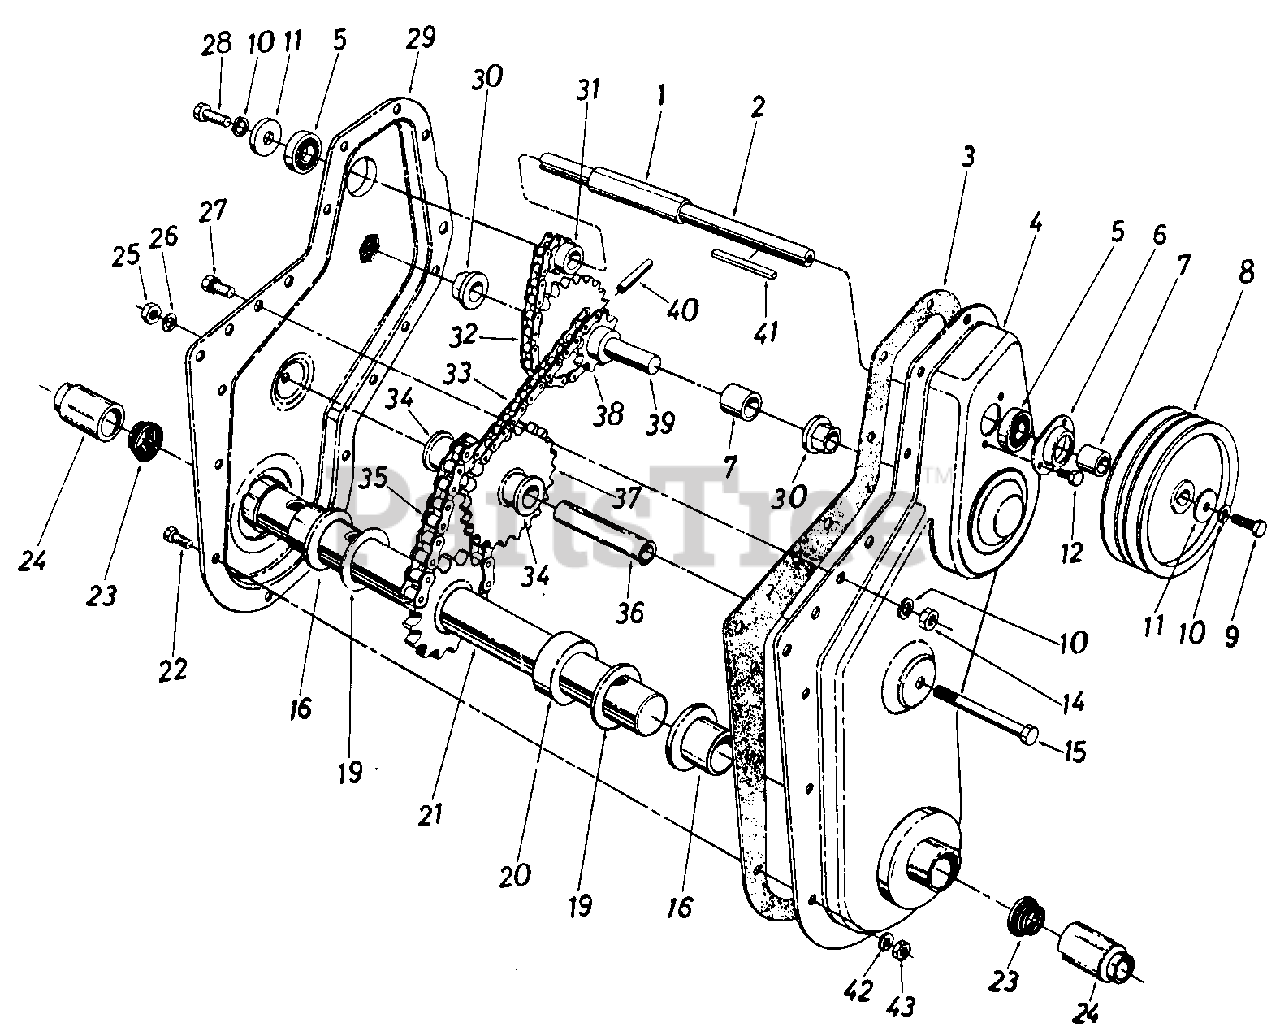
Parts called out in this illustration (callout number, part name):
2	SHAFT-JACK
3	GASKET
4	CHAIN CASE HALF-LH
5	BEARING-BALL
6	HOUSING-BRG
7	SPACER-.635 ID X .88 OD X 1.03
9	SCREW-HEX 5/16-18 X 10 SPEC
10	WASHER-LOCK-5/16
11	WASHER-FL-.312 X 1.125 X .125
12	SCREW-HEX WASH SF TAPP
14	NUT-HEX 5/16-18
15	SCREW-HEX 3/8-16 X 3.25
16	BEARING-KING PIN
19	WASHER-FL-1.03 ID X 1.62 X .03 HD
21	SHAFT-TINE
22	SCREW-HEX 1/4-28 X .62
24	CAP-DUST
25	NUT-HEX 3/8-16
26	WASHER-LOCK-3/8
27	SCREW-HEX SEMS 5/16-18 X 1.00
28	SCREW-HEX 5/16-18 X .62
29	CHAIN CASE HALF-RH
30	BEARING-HEX FLANGE
31	SPROCKET ASSY-10T
32	#41 CHAIN 1/2 PITCH X 34 LINKS E
33	#420 CHAIN 1/2 PITCH X 48 LINKS
34	BEARING-FLANGE .626 ID
35	#50 CHAIN 5/8 PITCH X 28 LINKS
36	SHAFT-SPROCKET
37	SLEEVE ASSY-SPRKT
38	SLEEVE ASSY-SPRKT
39	SHAFT-SPROCKET
40	PIN-SPRING SPIRAL 1/4X1.5 HEAVY DT
41	KEY-SQ 3/16X1.50
42	LOCK WASHER 1/4 DIA
43	NUT-HEX 1/4-28
